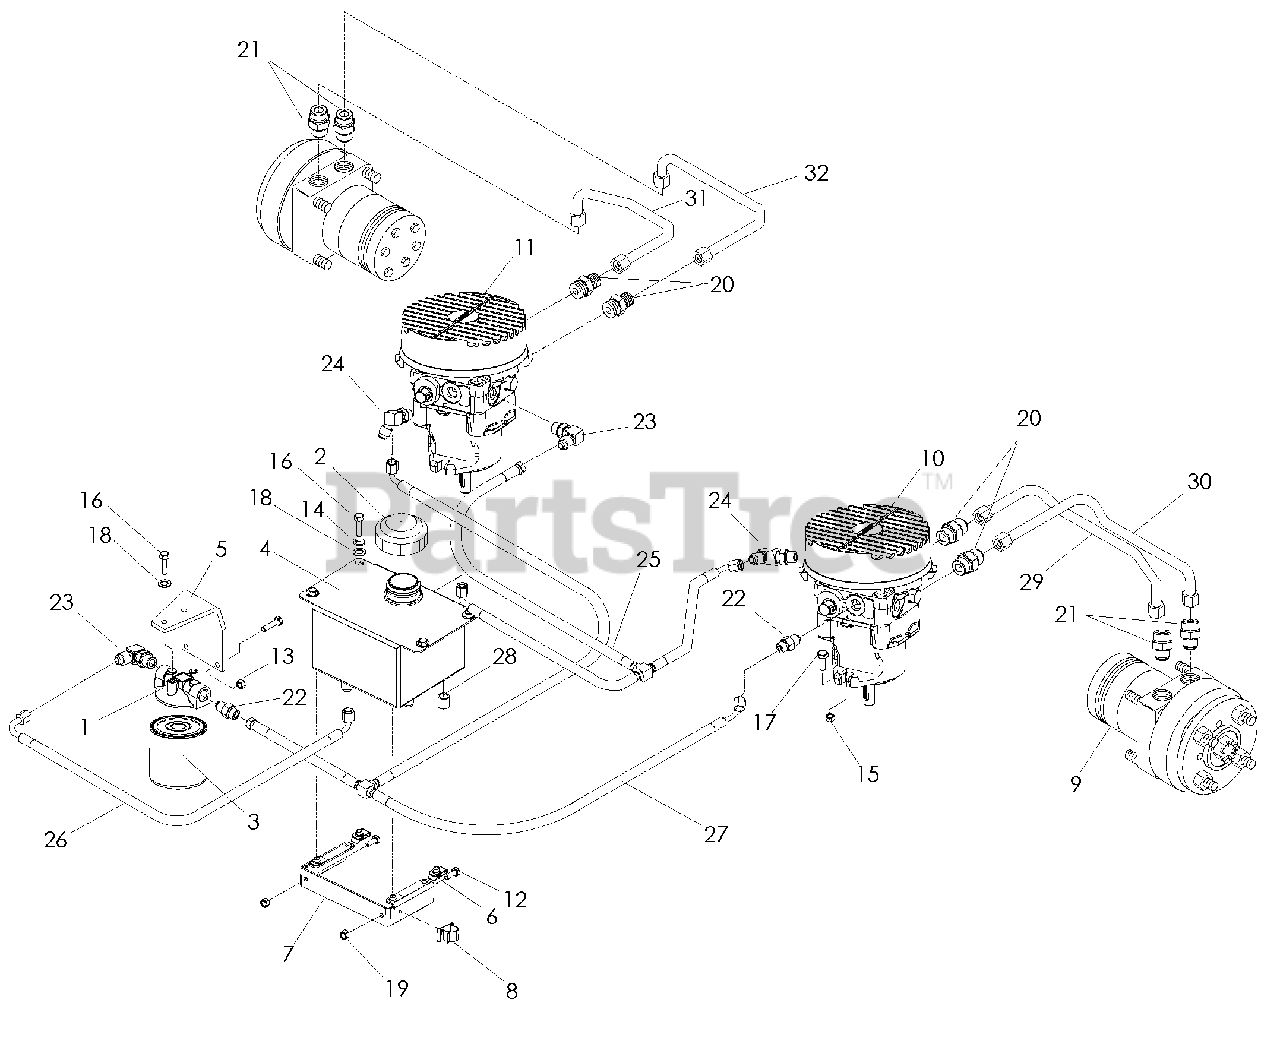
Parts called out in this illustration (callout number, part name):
1	Filter Head
2	Cap, Hydro Tank
5	Bracket, Filter
6	Retainer 1/4-20 U-Type
7	Mount, Tank
8	Wire Clip Push-Mount
9	Ti15 Wheel Motor
10	Pump 10Cc W/Fan Lt
11	Pump 10Cc W/Fan Rt
12	Hcs 5/16-18 X 3/4
13	Nut 1/4-20 Hex Nyloc
14	Washer 1/4 Split Lock
15	Nut 3/8-16 Hex Ctr Lk
16	Hcs 1/4-20 X 3/4
17	Hcs 3/8-16 X 1 Whizlk
18	Washer 1/4 Flat
19	Nut 5/16-18 Hex Nyloc
20	Fitting, Straight
21	Fitting, Straight
22	Fitting, Straight
23	Fitting, Elbow
24	Fitting, Elbow
25	T" Assem, Return
26	Hose, Tank
27	T" Assem, Supply
29	Hydraulic Line
30	Hydraulic Line
31	Hydraulic Line
32	Hydraulic Line
